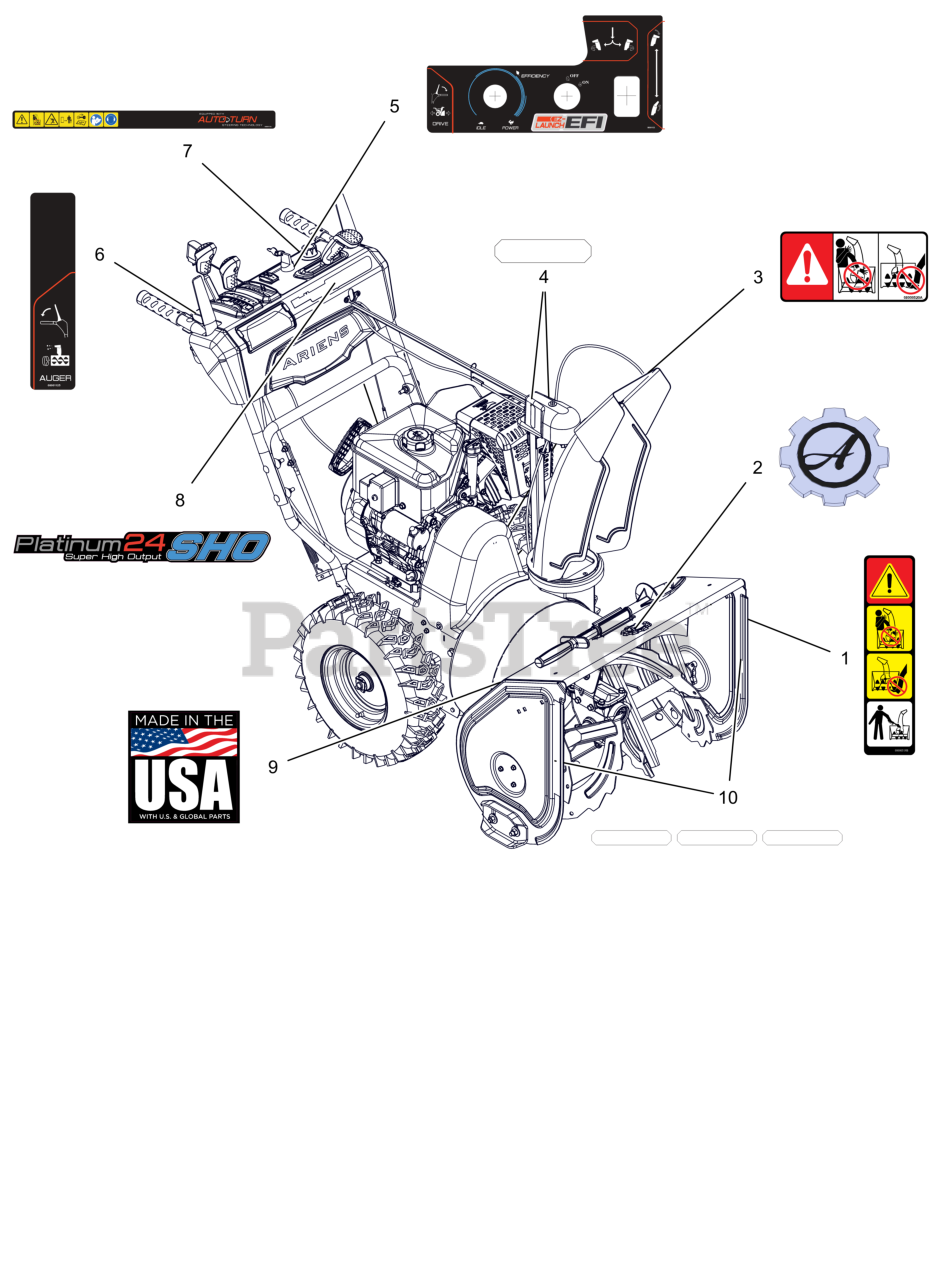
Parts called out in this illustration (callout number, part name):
1	DECAL, DANGER - ROTATING PARTS
2	DECAL, ARIENS - GEAR BADGE
3	DECAL, DANGER
4	DECAL,REFLECTIVE,GEAR COVER
5	DECAL, CONTROL - QT EFI W/GEL
6	DECAL,CONTROL-RH CONTROL
7	DECAL,DASH - SAFETY/EFI
8	DECAL, DASH, PLATINUM 24 SHO
9	DECAL, MADE IN USA
10	DECAL,REFLECTIVE,HOUSING
